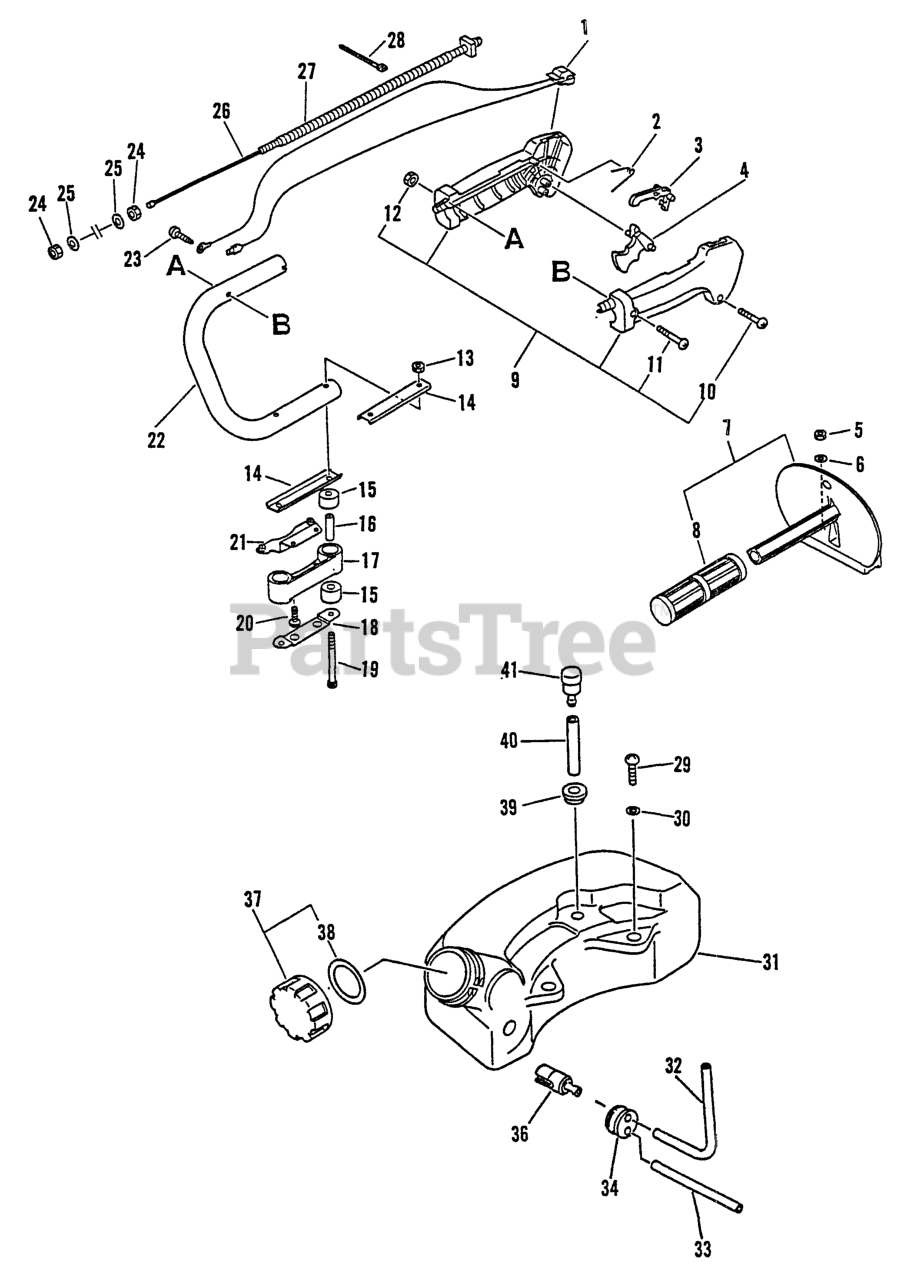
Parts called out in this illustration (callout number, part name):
1	IGNITION SWITCH ASSY
2	SPRING, TORSION
3	LOCKOUT, THROTTLE
4	TRIGGER, THROTTLE
5	NUT, LOCK 6
6	WASHER 6.5x13x1
7	BRACKET ASSY
9	CONTROL HANDLE KIT
10	SCREW 3x25
11	SCREW 5x30
13	NUT, LOCK M5
16	SPACER
17	BRACKET, HANDLE
19	BOLT 5x60
20	SCREW 5x16
22	HANDLE, REAR
23	SCREW 5x10
25	WASHER 6.5x11.5x0.8
26	CABLE, THROTTLE
28	TIE, CABLE
29	SCREW 5x16
30	WASHER 5.5x12x0.8
31	TANK, FUEL
32	PIPE, FUEL
33	PIPE, FUEL RETURN 3x6x110
34	GROMMET, FUEL
36	FILTER, FUEL
37	CAP ASSY
38	GASKET, FUEL CAP
39	GROMMET
40	PIPE, FUEL
41	VENT ASSY
